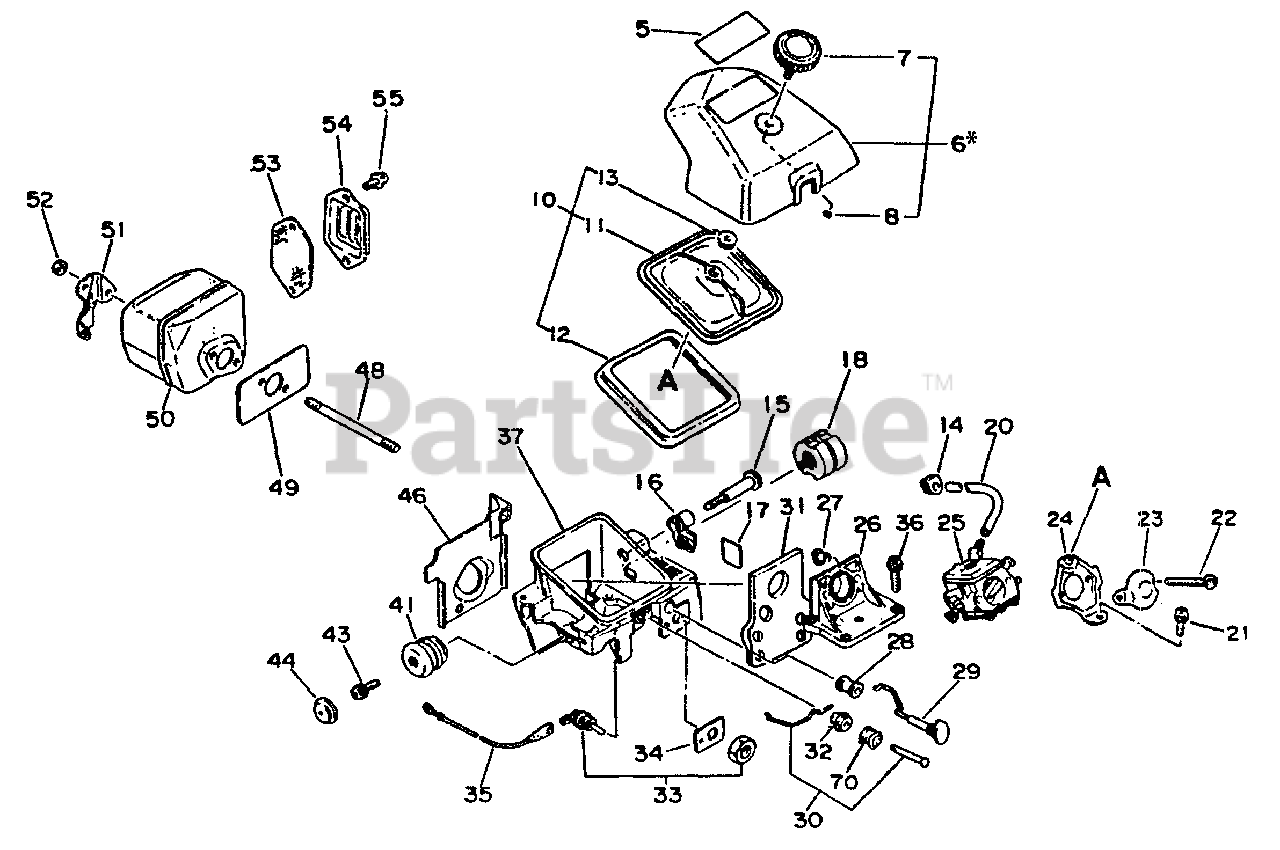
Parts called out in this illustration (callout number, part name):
5	LABEL
6	AIR FILTER COVER ASSY
7	THUMBSCREW
8	O-RING 3
10	AIR FILTER COVER ASSY
11	FILTER, AIR
12	GASKET, CARBURETOR CASE
14	BUSHING
20	PIPE, IMPULSE
21	SCREW - 5×14
22	SCREW - 5×55
24	BRACKET, AIR FILTER
25	CARBURETOR
26	INSULATOR
27	NUT
28	GROMMET, CHOKE
29	ROD, CHOKE
30	ROD, THROTTLE
31	SEAL
32	GROMMET, THROTTLE ROD
33	SWITCH, ON-OFF
34	LABEL, STOP
35	LEAD - GROUND
36	SCREW - 5×25
37	CASE, CARBURETOR
41	CUSHION
43	SCREW - 5×10
44	CAP, CUSHION
46	PLATE, GUIDE
48	STUD
49	GASKET, EXHAUST
50	MUFFLER
52	LOCKNUT - 5
53	SCREEN, SPARK ARRESTER
54	COVER, MUFFLER
55	SCREW 4×8
